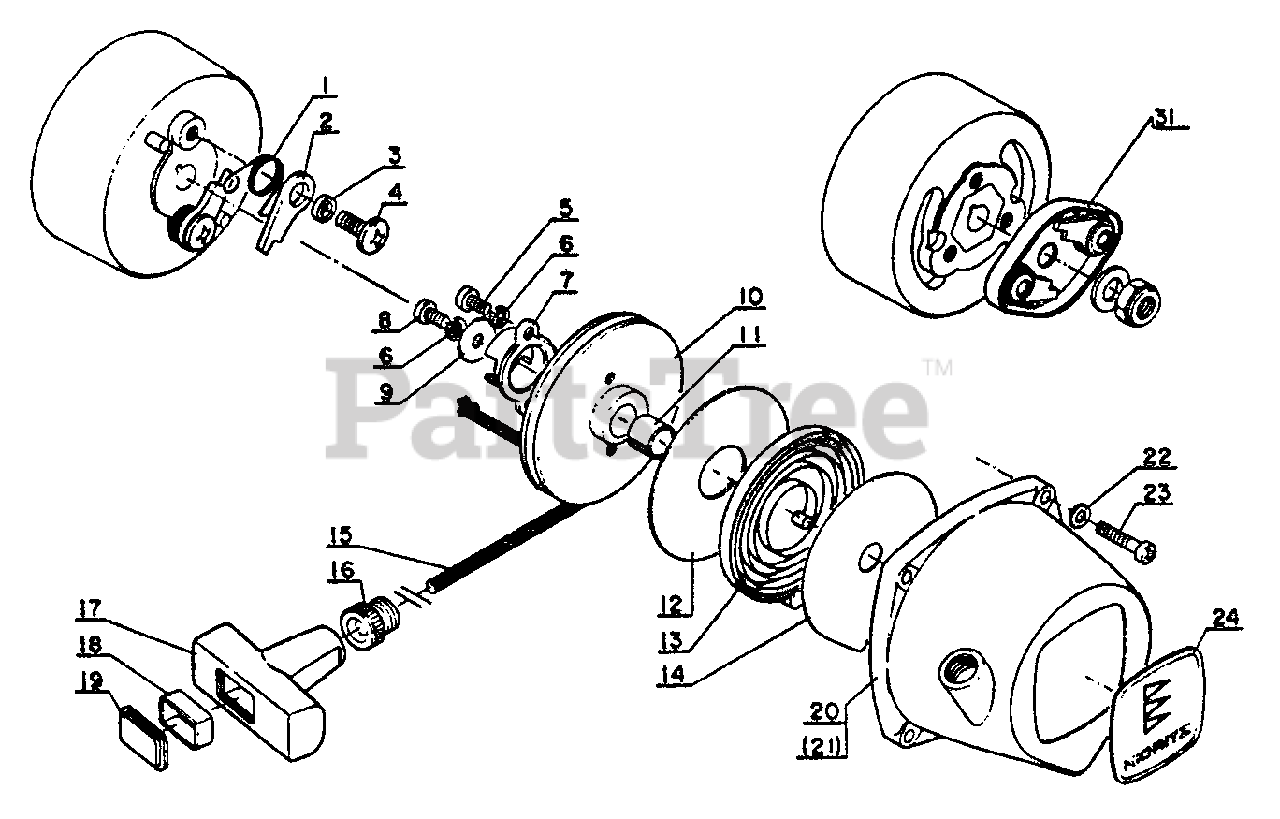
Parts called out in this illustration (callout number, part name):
1	SPRING, RETURN
2	PAWL, STARTER
4	SCREW
5	SCREW - 4X8
6	LOCKWASHER - 4
7	CATCHER, PAWL
8	STARTER ASSY
8	SCREW - 4X6
10	REEL, ROPE
12	PLATE, STARTER
13	SPRING, REWIND
14	PLATE, STARTER
15	ROPE, STARTER - 3.5X850
16	GUIDE, ROPE
17	GRIP, STARTER
18	RING, RETAINING
20	CASE, STARTER
22	WASHER - 4
23	SCREW - 4X20
24	NAME PLATE
31	STARTER PAWL ASSY
